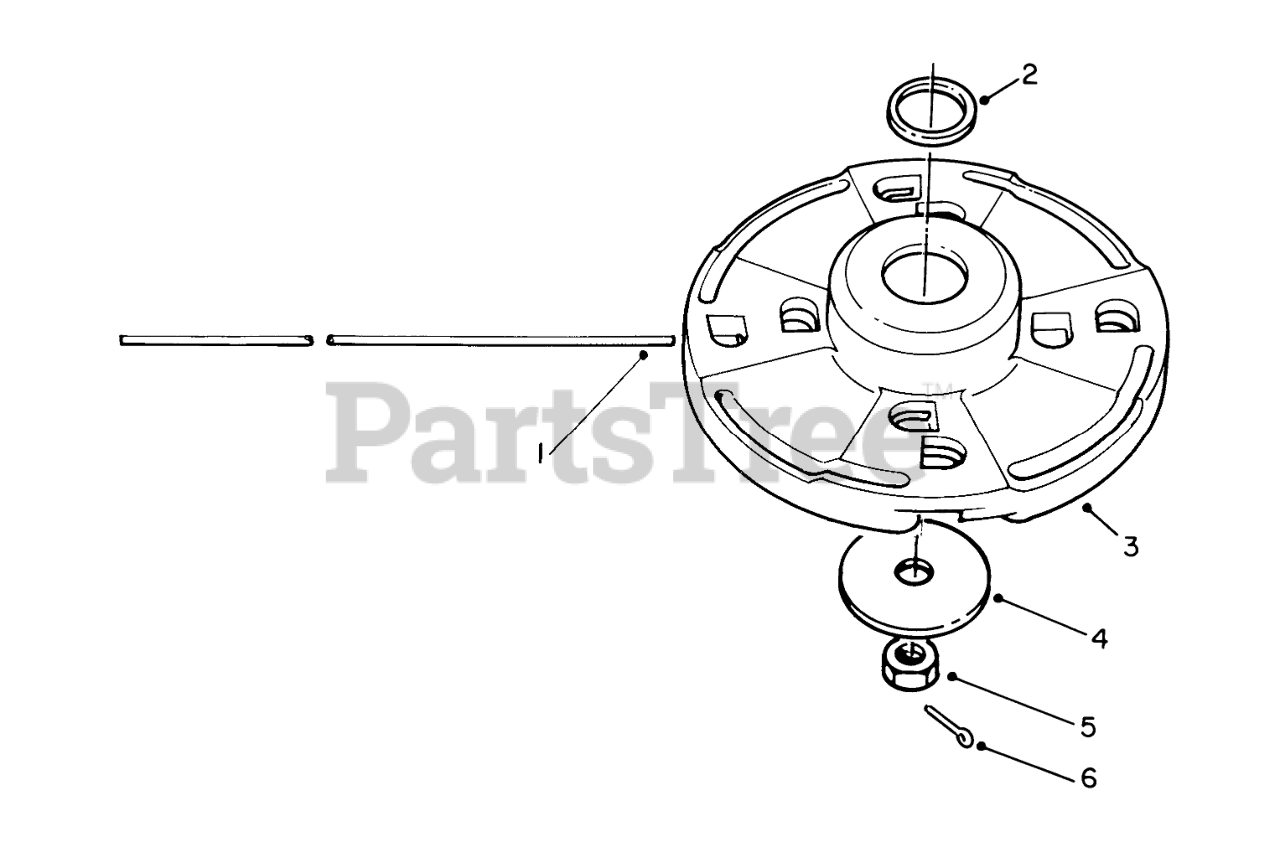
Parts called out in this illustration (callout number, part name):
1	LINE PACK (100)
2	SPACER
3	Head Assembly (Incl. Ref. #2)
4	WASHER
6	1/16 X 1 LG COTTER PIN
